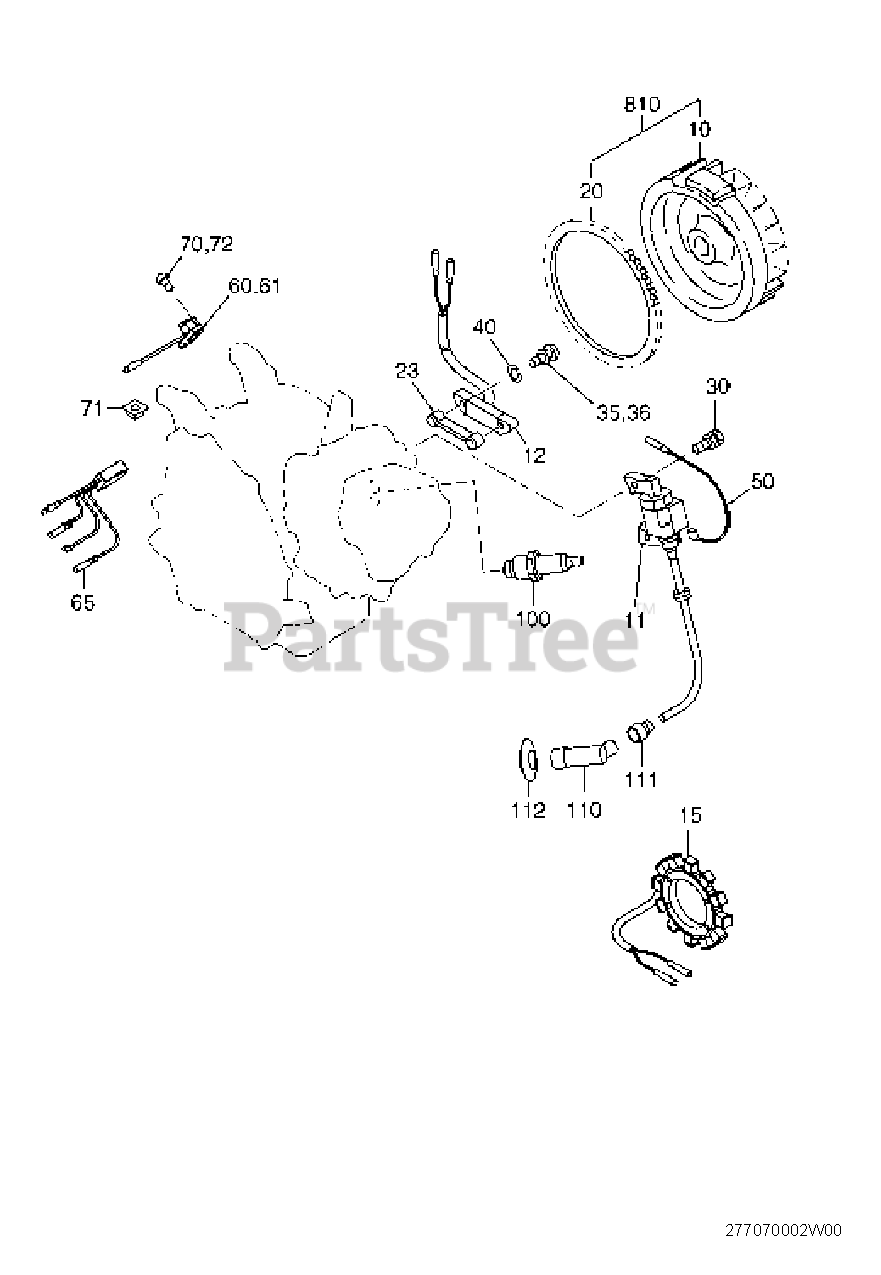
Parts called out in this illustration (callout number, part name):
11	IGNITION COIL CP
30	BOLT AND WASHER AY
110	SPARK PLUG CAP
